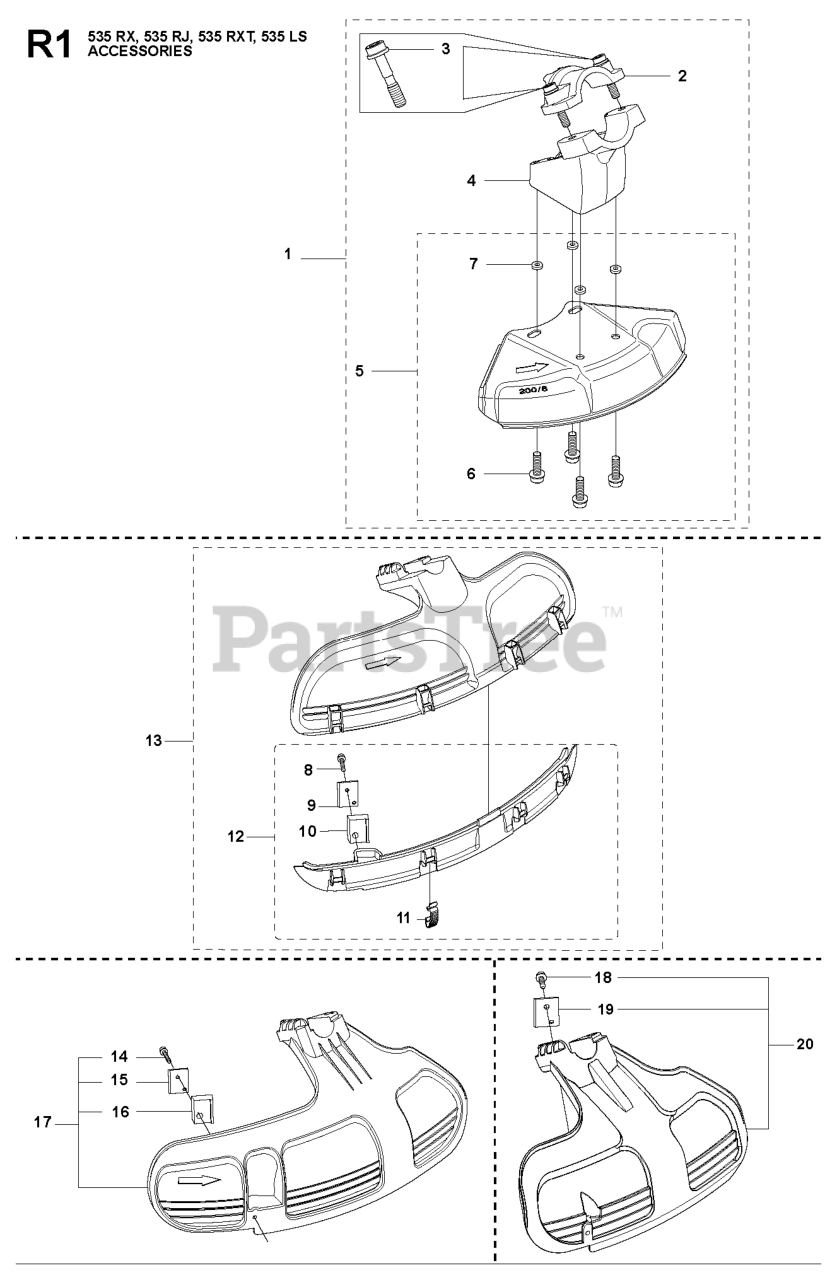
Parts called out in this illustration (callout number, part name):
1	ADAPTER
2	CLAMP
3	SCREW IHSCFMO
4	ADAPTER
5	BLADE GUARD
7	LOCKING NUT
8	SCREW
10	DISTANSBLOCK
12	SPLASH GUARD
13	COMBI PROTECTOR
16	DISTANSBLOCK
17	PROTECTOR
20	TRIMMER GUARD ASSY
